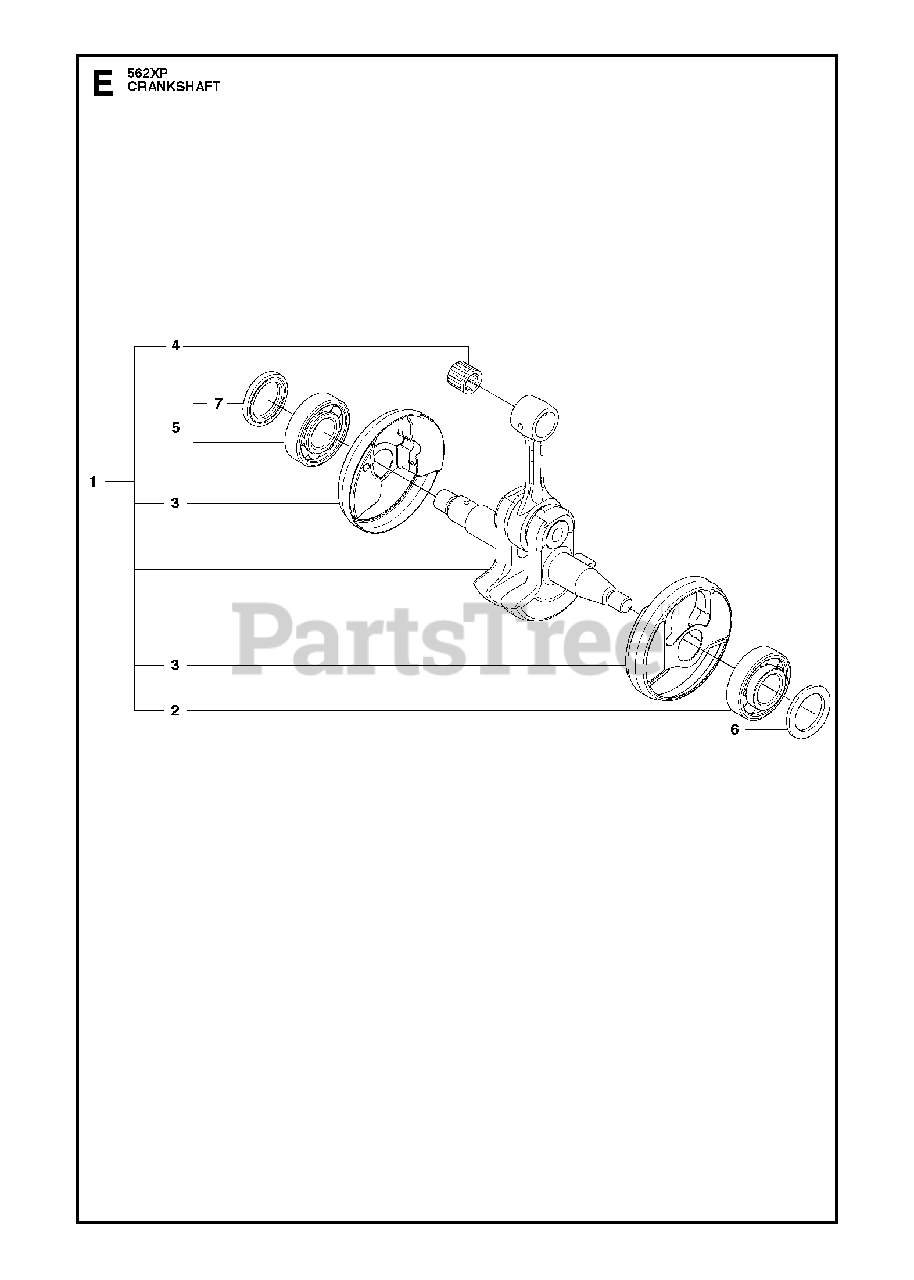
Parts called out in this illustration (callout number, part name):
1	CRANKSHAFT ASSY
2	BALL BEARING
3	CUP
4	NEEDLE BEARING
5	BALL BEARING
6	RADIAL SEAL
7	SEALING
